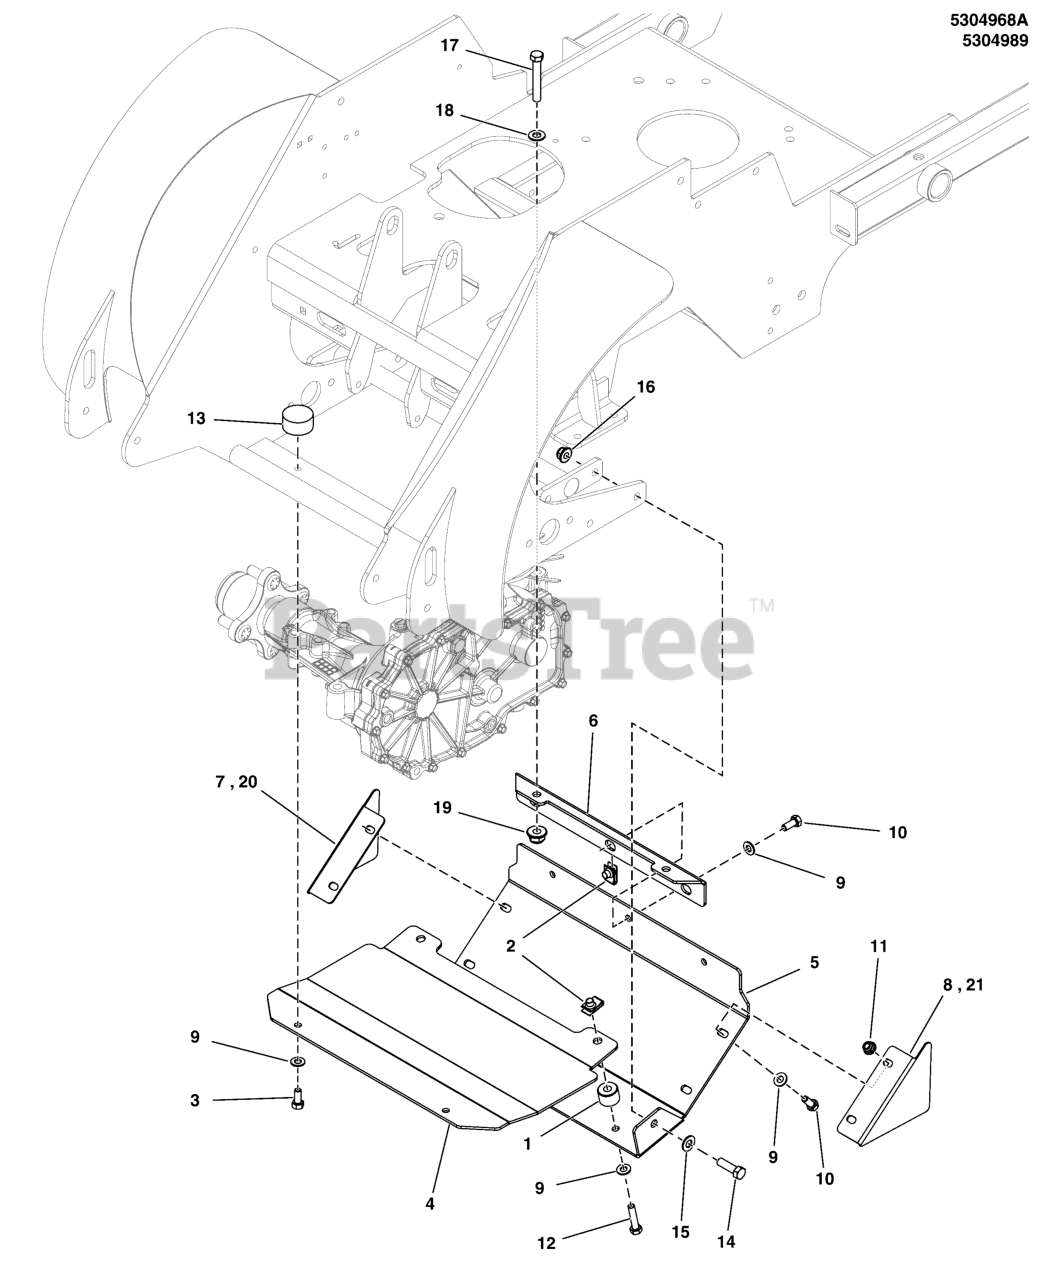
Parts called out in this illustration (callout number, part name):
1	SPACER, .39 X 1.00 X .75, CZ
2	BODY CLIP, 5/16-18-7GA MATERIAL
3	BOLT, 5/16-18 X 1 GD5 CZ
4	PLATE, PLATFORM GUARD, REAR, CE - BLK
5	PLATE, PLATFORM GUARD, FRONT, CE - BLK
6	PLATE, MOUNT, PLATFORM GUARD - BLK
7	PLATE, DEFLECTOR, LH, 36CE - BLK
8	PLATE, DEFLECTOR, RH, 36CE - BLK
9	WASHER, 5/16" SAE
10	BOLT, 5/16-18 X 3/4 GD5
11	NUT, 5/16-18 HEX NYLOCK FLANGE
12	BOLT, 5/16-18 X 1-1/2 GD5 CZ
13	BUMPER, RUBBER
14	BOLT, 3/8-16 X 1-1/4" GD5 CZ
15	WASHER, 3/8 SAE
16	NUT, 3/8-16 HEX NYLOCK FLANGE
17	BOLT, 3/8-16 X 2-1/2" GD5 CZ
18	WASHER, 3/8 SAE
19	NUT, 3/8-16 HEX NYLOCK FLANGE
20	PLATE, DEFLECTOR, LH, 48CE - BLK
21	PLATE, DEFLECTOR, RH, 48CE - BLK
